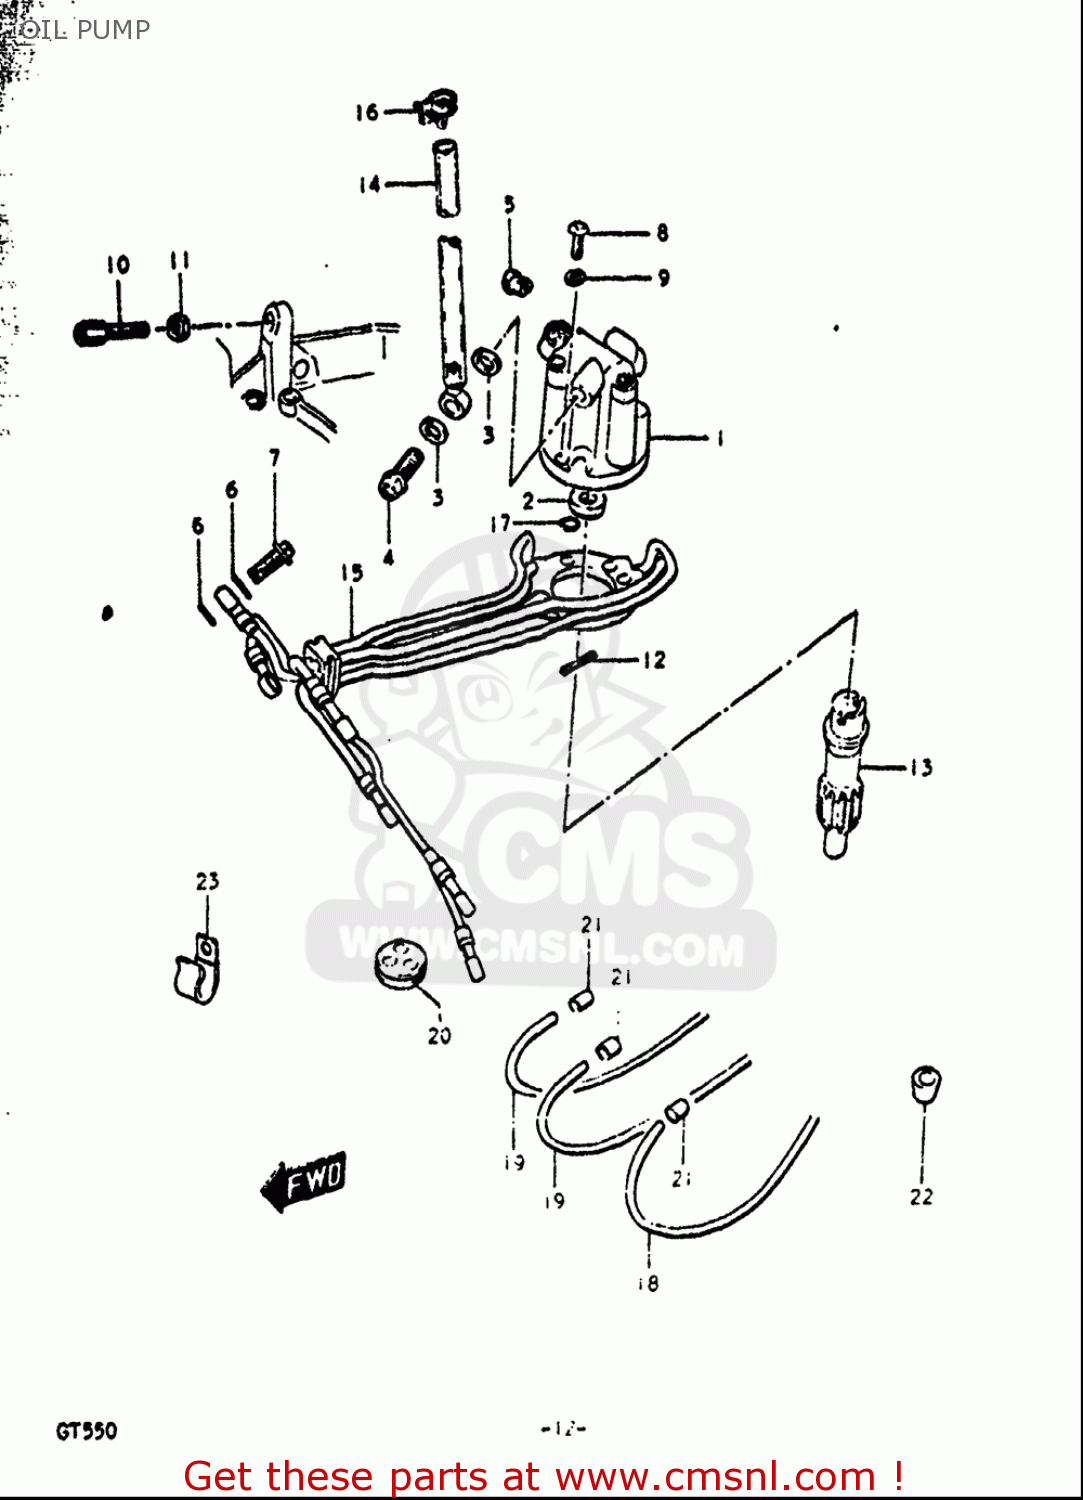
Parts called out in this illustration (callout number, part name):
2	SEAL,OIL(8X16X4)
3	GASKET(6.2X11X1).2 (NAS)
4	UNION BOLT
5	TERMINAL,CABLE
6	GASKET(6.2X11X1).2 (NAS)
7	UNION BOLT
8	SCREW
9	WASHER,LOCK
10	BOLT
11	NUT
12	PIN(3X13.8)
14	HOSE,INLET
16	CLAMP
17	O RING(D:1.9,ID:3.8)
18	HOSE(2X5X600)
19	HOSE(2X5X600)
21	CLIP
23	CLAMP(L:120 T:1.0)
